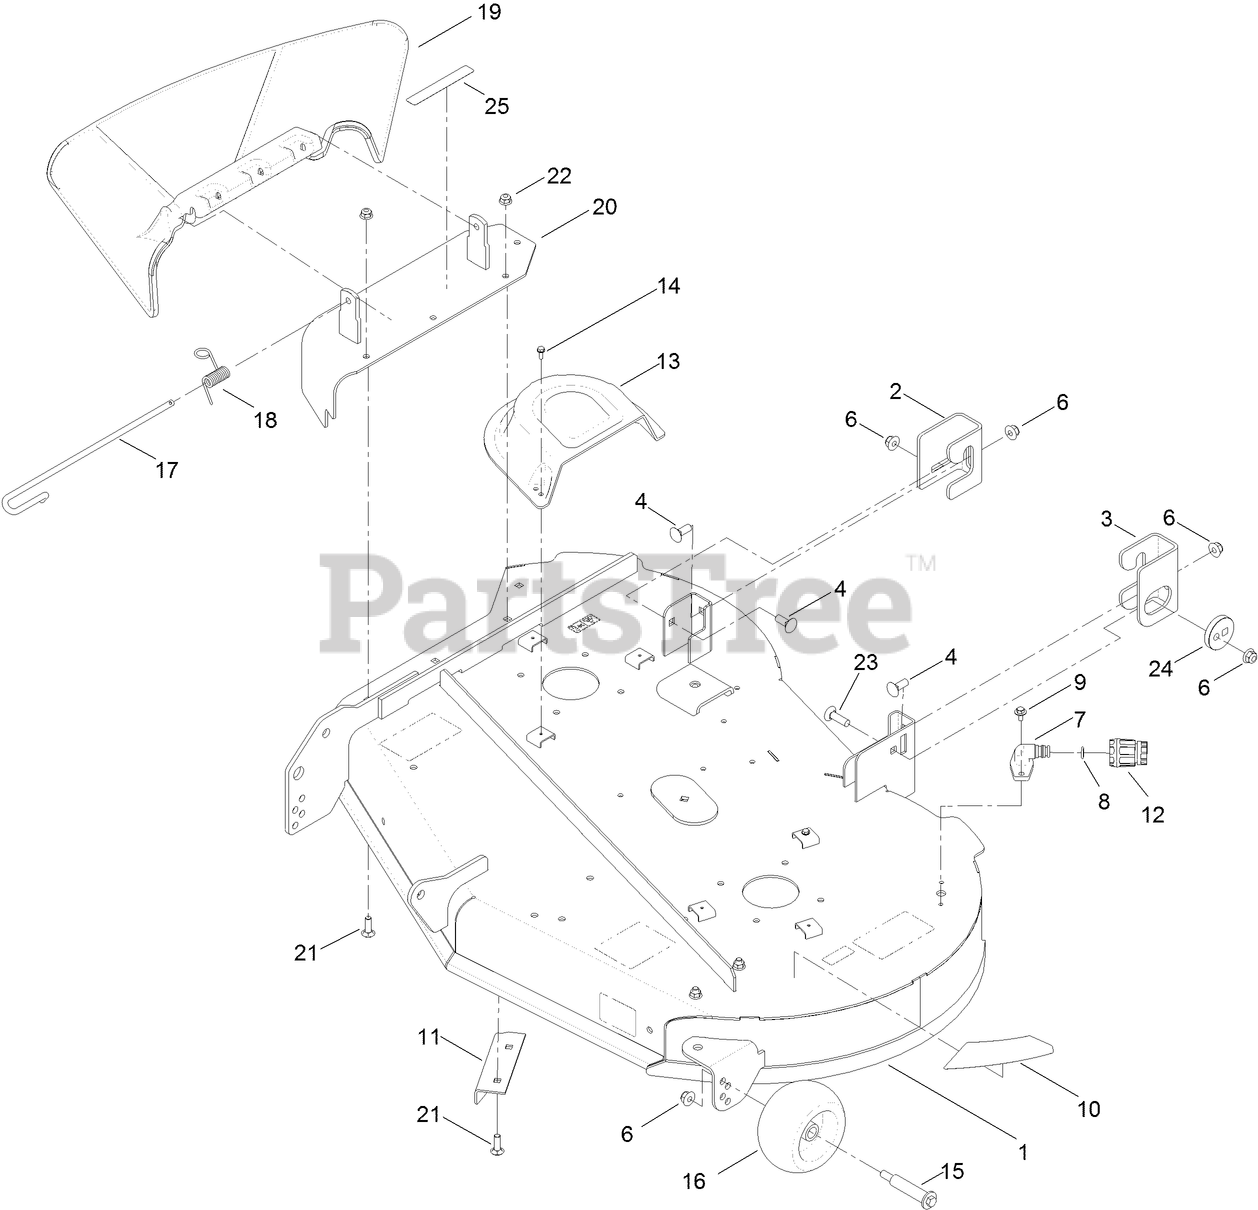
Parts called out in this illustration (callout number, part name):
1	42 INCH DECK AND DECAL ASM
3	BRACKET-HANGER, LH
4	BOLT-CARR
6	NUT-HF, NI
8	O-RING
9	SCREW-HHFTF
10	DECAL-DECK
11	BAFFLE-CUTOFF
12	CONNECTOR-HOSE
13	COVER-BELT
14	SCREW-TAPTITE
15	BOLT-SHOULDER
16	ROLLER-SCALP, ANTI
17	PIN-CHUTE
18	SPRING-TORSION
19	DEFLECTOR-DISCHARGE
20	DISCHARGE COVER ASM
21	SCREW-CARR
22	NUT-HF, NI
23	SCREW-CARR
24	ECCENTRIC
25	DECAL-DANGER
